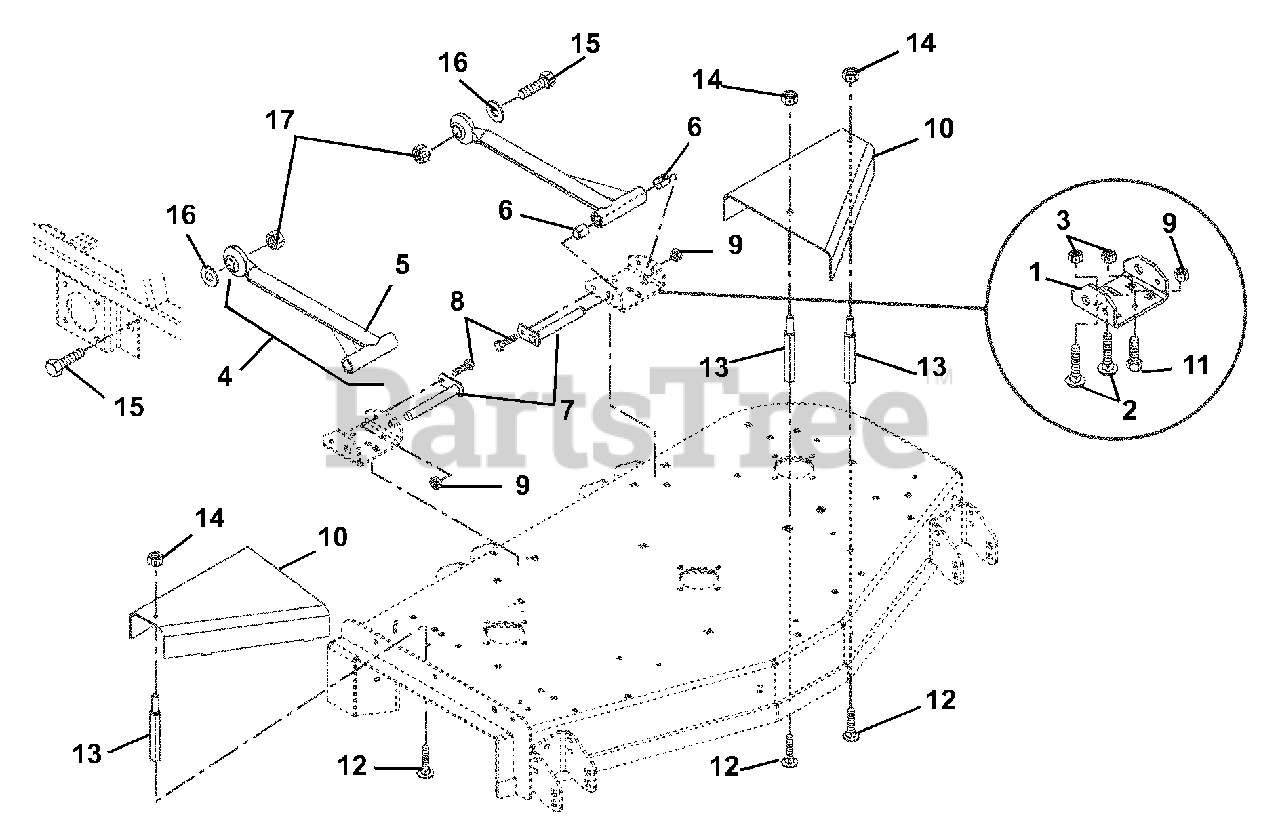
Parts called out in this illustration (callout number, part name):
1	Bracket, Mower Mounting (Rear)
2	Bolt, Round Head Square Neck .50-13 x .75 Grade 5
3	Nut, Locking Center Jam .50-13
4	Assembly, Mower Mounting Arm
5	Weldment, Mower Mounting Arm
6	Bearing .75 x .875 x 1.00
7	Weldment, Mower Mounting Pin
8	Bolt, Hex .38-16 x 1.00 Grade 5
9	Nut, Locking Top Flange .38-16
10	Guard, Pulley Left Hand
10	Guard, Pulley Right Hand
10	Guard, Right Hand Pulley
10	Guard, Left Hand Pulley
11	Bolt, Round Head Square Neck .38-16 x .75 Grade 5
12	Bolt, Round Head Square Neck .31-18 x .75
13	Standoff 2.75 x 5/16-18
14	Nut, Locking Top Flange .31-18
15	Bolt, Hex .875-9 x 2.75 Grade 5
16	Washer, Flat Steel .875 x 1.50 x .120
17	Nut, Locking Center .875-9
